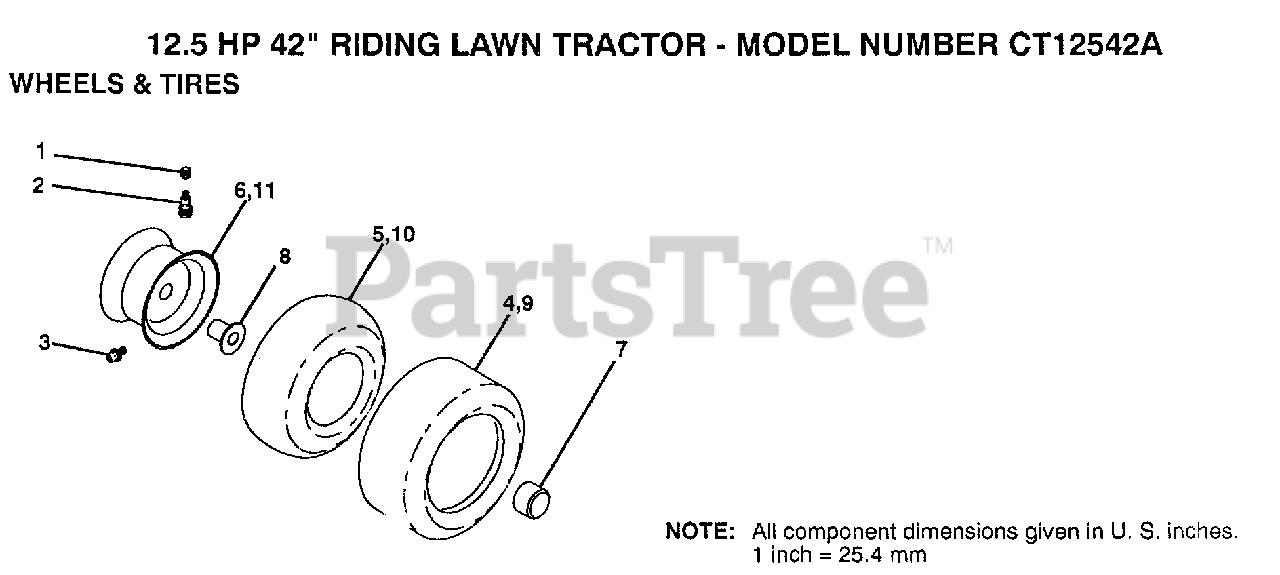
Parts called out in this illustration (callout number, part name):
1	VALVE CAP
2	VALVE STEM LT
3	FITTING LT
5	TUBE.5.3/4.5/6
7	HUB CAP
8	"FLANGE, BEARING"
10	TUBE.18X9.5-8
